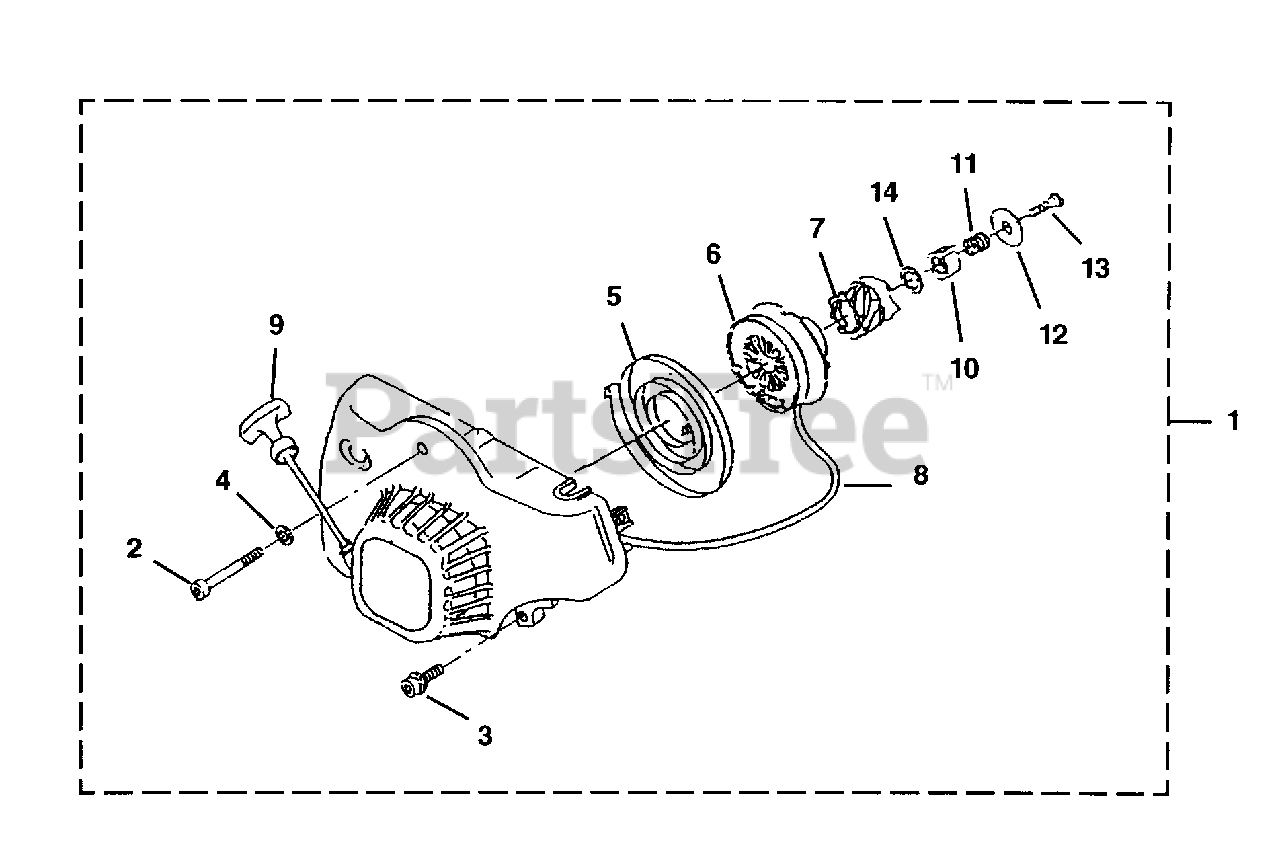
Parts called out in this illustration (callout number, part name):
1	STARTER ASSEMBLY
2	SCREW - Socket Hd (M5 X 50)
3	SCREW - Socket Hd (M5 x 22 W)
8	ROPE - Starter
10	RATCHET GUIDE
11	SPRING - Friction
13	SCREW
14	THRUST WASHER
